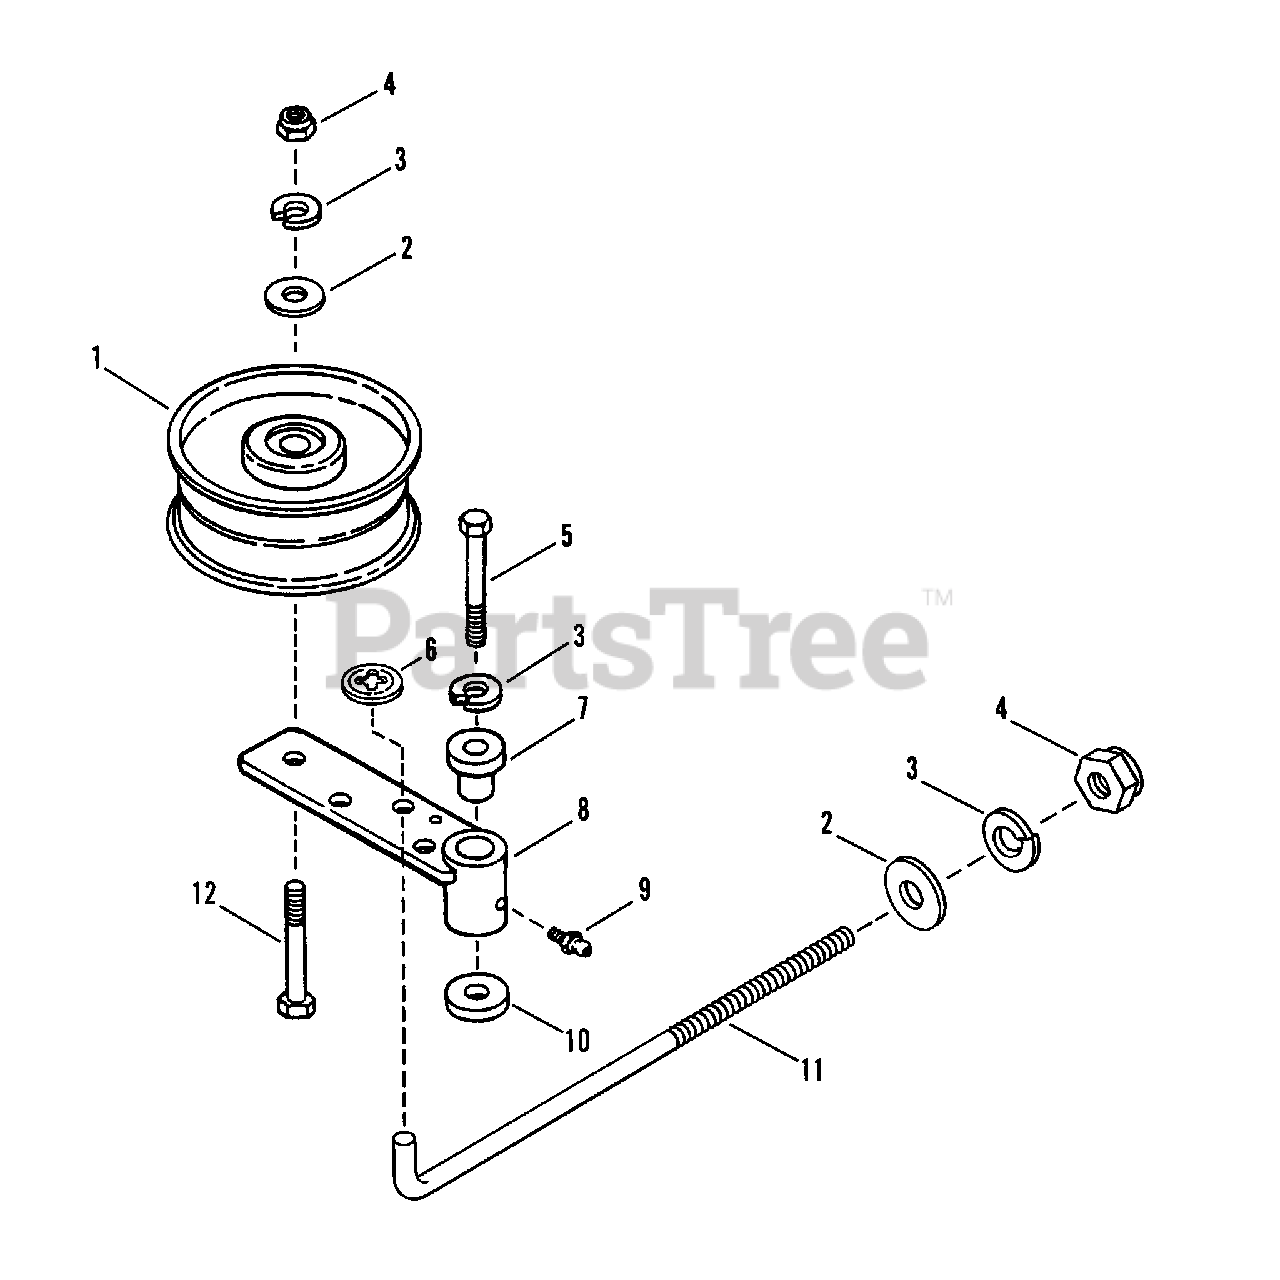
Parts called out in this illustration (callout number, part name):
1	PULLEY, Idler, 5.25
2	WASHER, 3/8" USS
3	WASHER, 3/8 Split Lock
4	NUT, 3/8-16 HEX NYLON LOCK
5	BOLT, 3/8-16 x 3" Hex Head Cap, Grade 5
6	RETAINER, 3/8"
7	SPACER, Pivot
8	WELDMENT. 48" Blade/Blade Deck Idler
9	FITTING, Lube
10	BUSHING
11	ROD, 11.25"
12	SCREW, 3/8-16 x 1 3/4" Hex Head Cap, Grade 8
